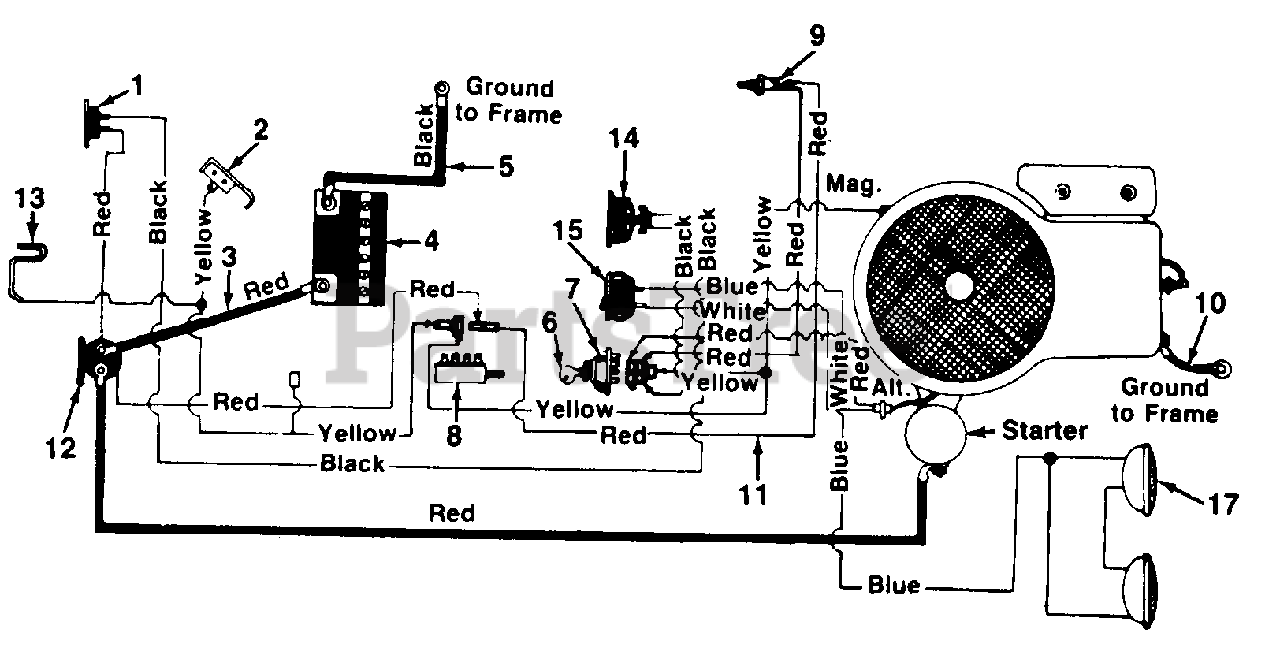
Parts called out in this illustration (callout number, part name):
1	Circuit Breaker
2	Reverse Safety Switch
3	Electric Wire
4	12 V-Battery
5	Ground Wire 9.0" Lg.
6	Ignition Key
7	Ignition Switch
8	Safety Switch
9	Safety Switch
10	Ground Wire 7.25" Lg.
11	Wire Harness
12	Solenoid
13	Spring Switch
14	Ammeter
15	Light Switch
17	Headlight
